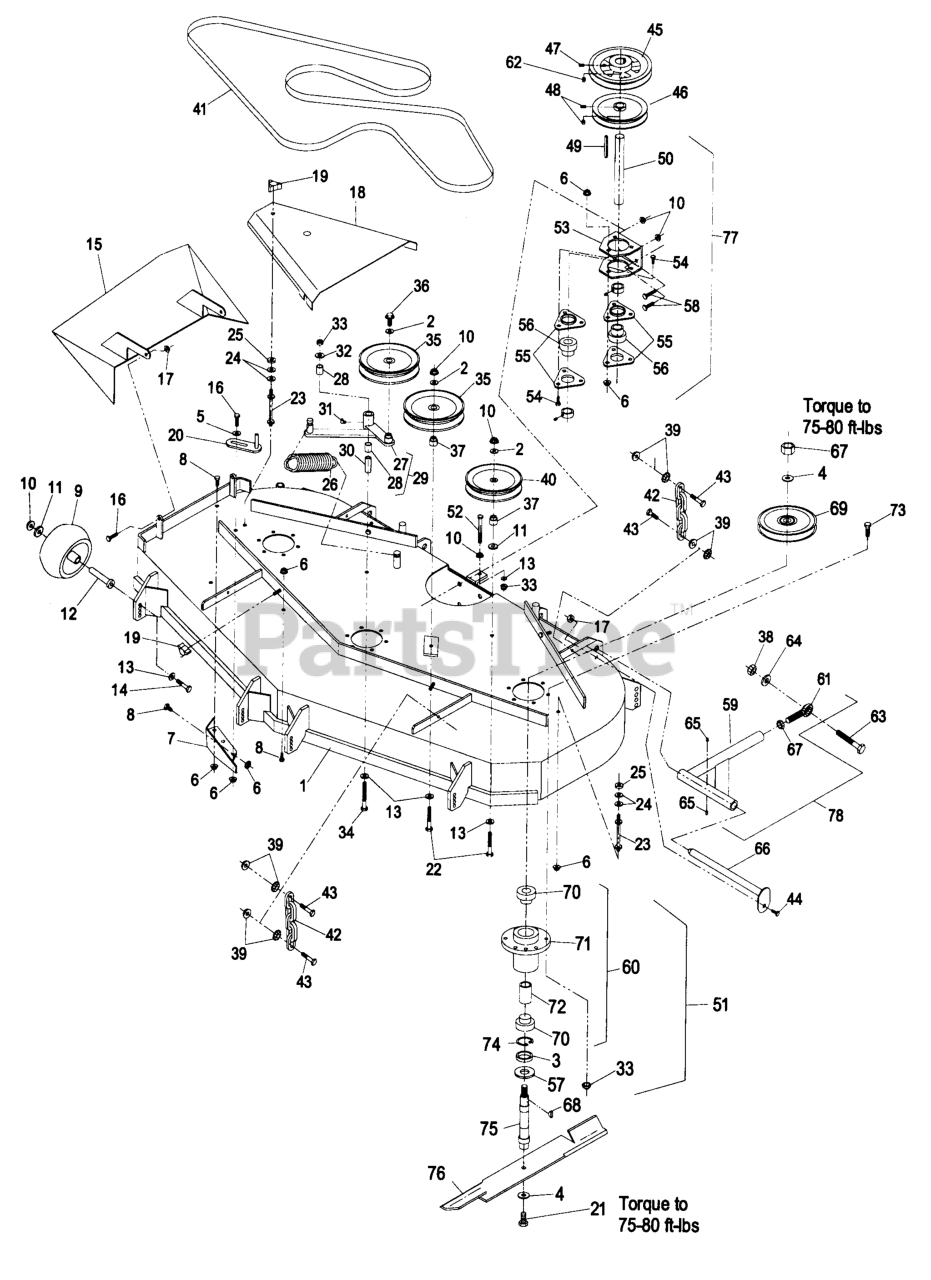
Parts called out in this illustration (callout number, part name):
3	SPACER-PULLEY/BEARING
4	WASHER-SPRING
5	WASHER-SPRING
7	WLD,BAFFLE DISCHARGE
9	ROLLER-SCALP, ANTI
12	BUSHING-ROLLER
15	WLD,CHUTE DISCHARGE
18	SHIELD,BELT 52
19	KNOB-3 PRONG
20	GUIDE-BELT
23	STUD-SHIELD, BELT (SHORT)
28	SLEEVE-BEARING
30	BUSHING
37	BUSHING-IDLER
40	PULLEY-IDLER
41	BELT,BLADE DRIVE 52
42	CHAIN-LIFT, DECK
43	SCREW-CAP, HH
46	SHEAVE,SPLIT STEEL
48	SCREW-SET
49	KEY,MACH 1/4X1/4X2-5/8
50	JACKSHAFT,DECK DRIVE
51	CUTTER HOUSING ASSY
53	BRACKET,JACKSHAFT
55	HOUSING-FLANGE
56	BEARING,W/COLLAR
57	GUARD-BEARING, BOTTOM
61	BALLJOINT-SPHERICAL
62	SCREW-SET
66	PIN-STRUT
69	SHEAVE,BLADE DRIVE
70	BEARING
72	SPACER-BEARING
75	SHAFT,SPINDLE SHORT
77	DK DR. BRG. ASSY
